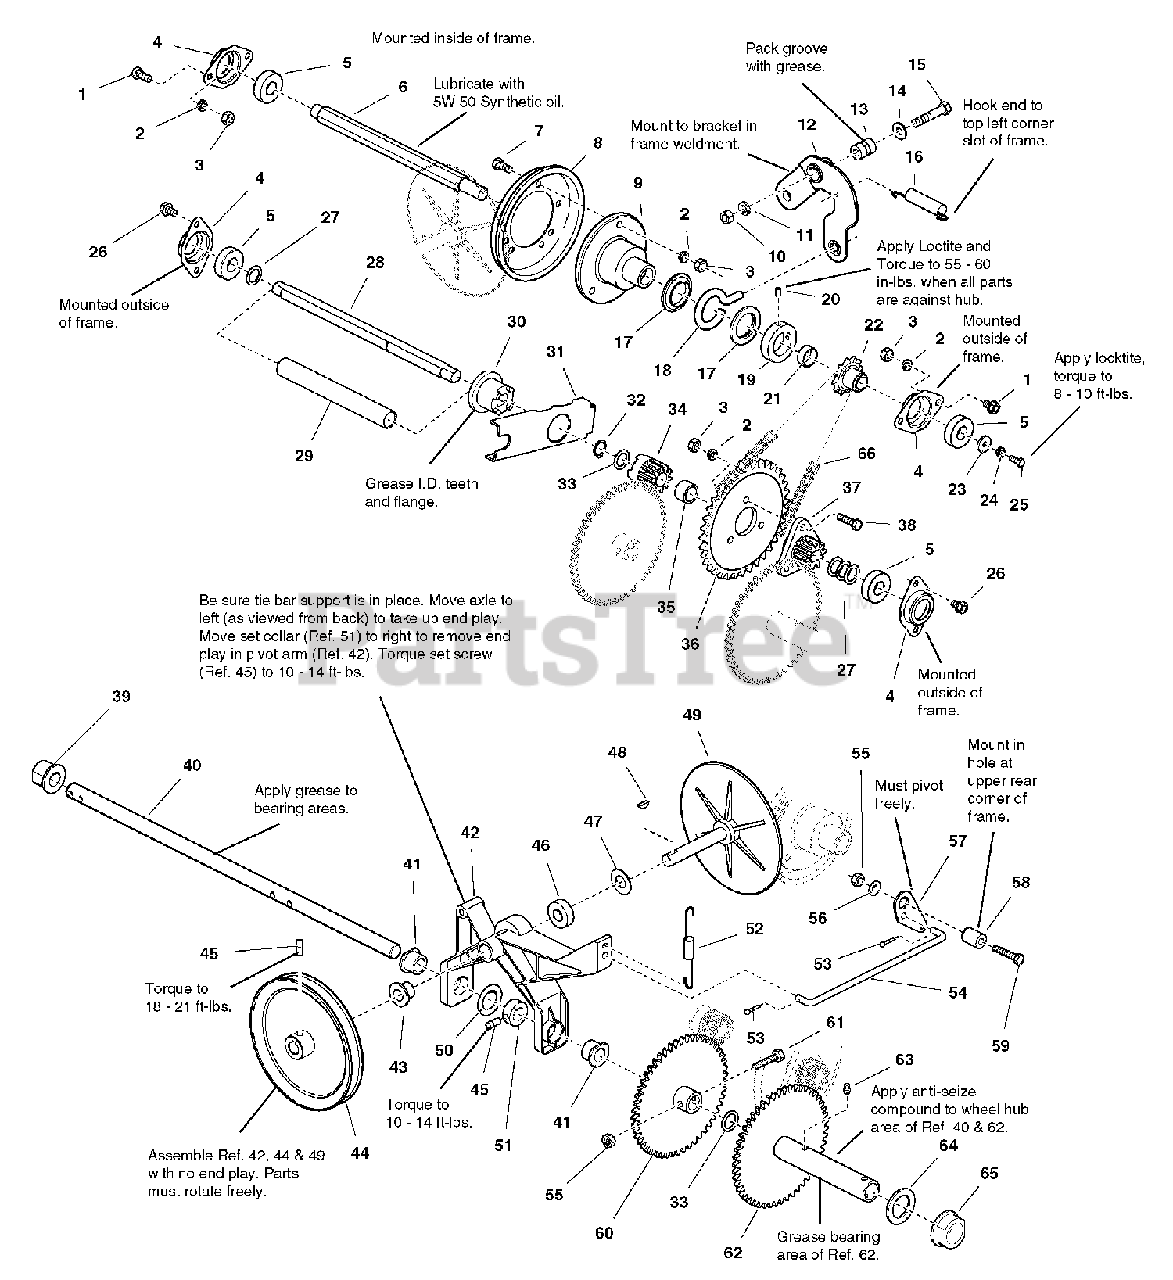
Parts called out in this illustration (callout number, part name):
1	CAPSCREW, Hex Head, 5/16-18 x 5/8
2	LOCKWASHER, 5/16
3	NUT, Hex, 5/16-18
4	RETAINER, Bearing
7	CAPSCREW, Hex Head, 5/16-18 x 3/4
8	DISC, Friction
9	HUB, Friction Disc
10	NUT, Hex, 3/8-16
11	LOCKWASHER, 3/8
12	ARM ASSEMBLY, Shift w/Bushings
13	BUSHING, Spacer
14	WASHER, Flat, 13/32
15	CAPSCREW, Hex Head, 3/8-16 x 2
16	SPRING
17	COLLAR, Thrust
20	SETSCREW, Square Head, 1/4-20 x 1/2
22	SPROCKET, 10 Tooth
23	WASHER, Flat, 1/4
24	LOCKWASHER, 1/4
25	CAPSCREW, Hex Head, 1 /4-20 x 5/8
26	CAPSCREW, Hex Head Taptite, 5/16-18 x 1/2
29	SPRING, Compression
30	CLUTCH, Sliding
31	ARM, Clutch
32	RING, Retaining
33	WASHER, 3/4
34	GEAR, 10 Tooth, Stationary, Clutch
35	SPACER
36	SPROCKET, 36 Tooth
37	GEAR, 10 Tooth, Double D
38	CAPSCREW, Hex Head, 5/16-18 x 1
42	ARM ASSEMBLY, Pivot w/Bushings (Includes Reference Numbers 41, 43 & 46)
44	PULLEY, Traction
45	SETSCREW, Square Head, 5/16-18 x 1/2
48	KEY, Woodruff, 3/16 x 5/8
49	DRIVE DISC W/SPINDLE
50	WASHER
51	SET COLLAR
52	SPRING
53	PIN, Cotter, 1/8 x 3/4
55	NUT, Hex, Lock, 5/16-18
56	WASHER, Flat, 11/32
58	BUSHING, Pivot
59	CAPSCREW, Hex Head, 5/16-18 x 1 -3/4
60	GEAR & HUB ASSEMBLY, 50 Tooth
61	CAPSCREW, Hex Head, 5/16-18 x 1-1/2
62	GEAR & HUB ASSEMBLY, w/Bushing, 50 Tooth
63	FITTING, Lube
66	CHAIN, Drive, #40
